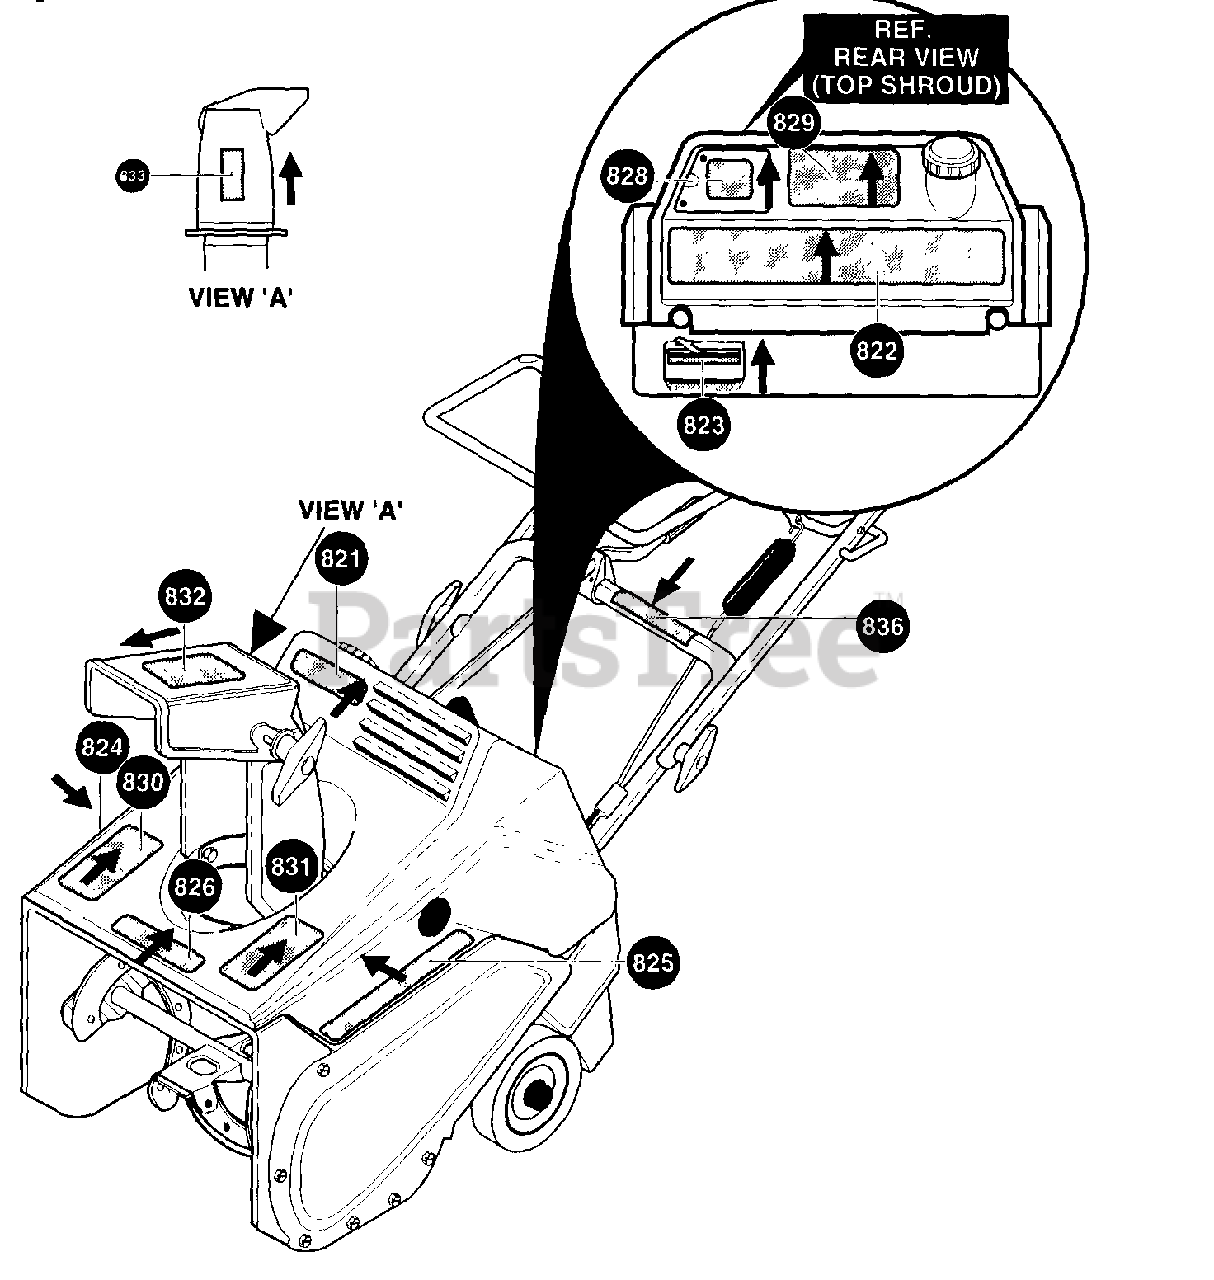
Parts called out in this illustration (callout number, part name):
821	DECAL, CROWN LOGO
822	DECAL, CONTROL PANEL ES
823	DECAL, OFF-CHOKE-ON
824	DECAL, ST521E SIDE PANEL
826	DECAL, HUSQVARNA TOP COVER
828	DECAL, FUEL MIX ENG/FR
829	DECAL, START INSTRU ENG/FR
830	DECAL, DANGER CHUTE ENG/FR
831	DECAL, DANGER AUGER ENG/FR
832	DECAL, HUSQ "CROWN"
833	DECAL, SAFETY INSTRU ENG/FR
836	DECAL, AUGER CONTROL BAR
